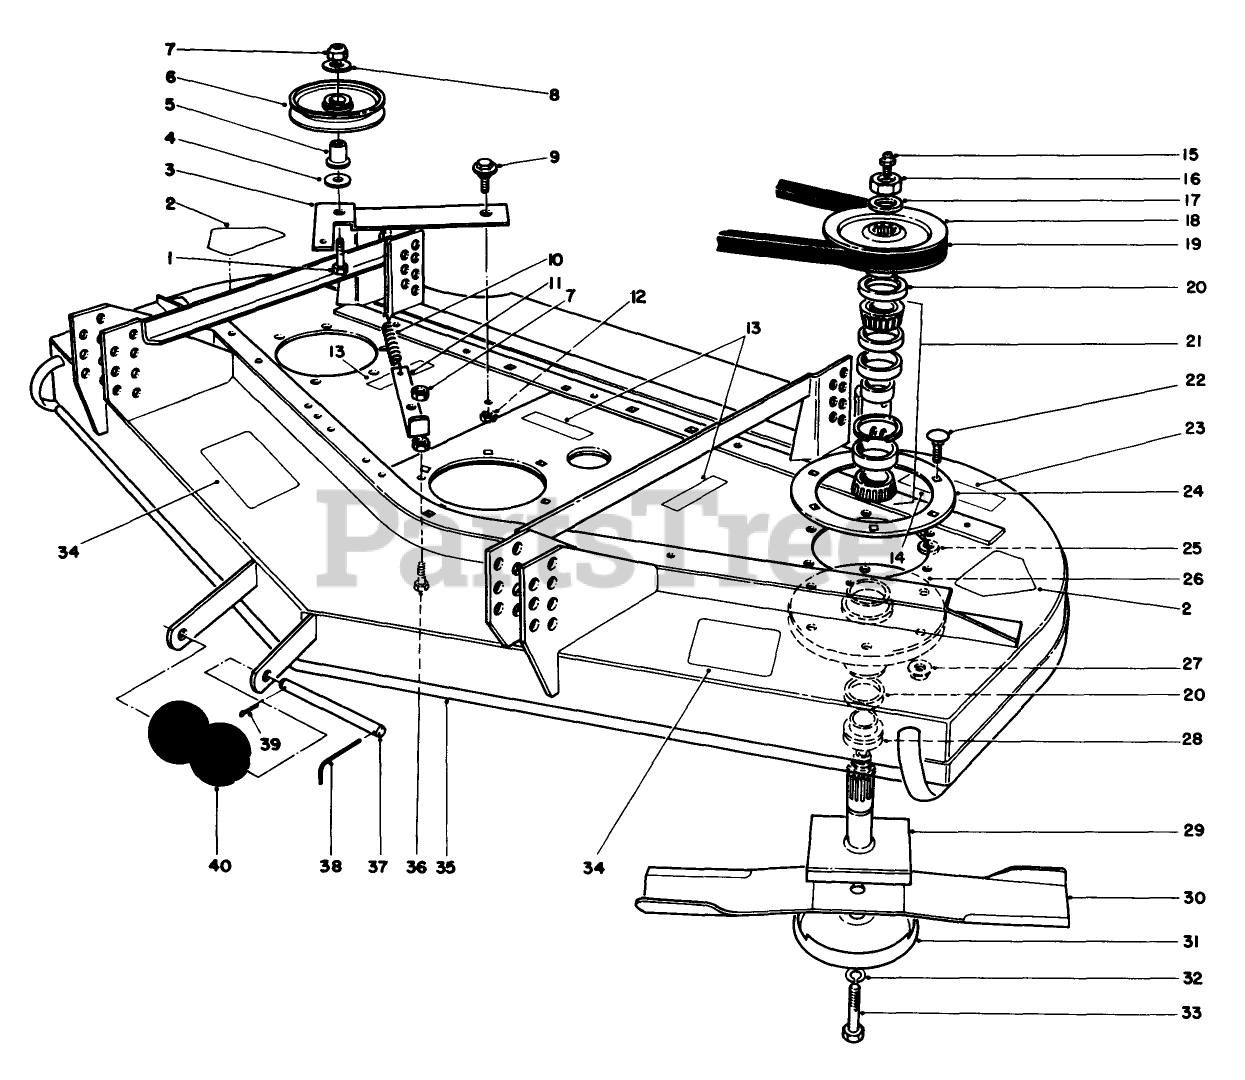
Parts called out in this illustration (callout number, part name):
1	SCREW-HH
1	FITTING-GREASE
2	DECAL-DANGER
2	NUT-HEX
3	Lever-Deck
3	WASHER
4	WASHER
4	PULLEY & HUB WA
5	BUSHING-PULLEY
5	SEAL-OIL
6	Pulley (Incl. Ref. #4 & 5)
6	BEARING ASM
7	NUT-LOCK, SIDE
7	HOUSING-SPINDLE
8	WASHER-FLAT
8	SPACER
9	SCREW-SHOULDER
9	SHAFT
10	SPRING-EXTENSION, DECK
11	Anchor-Spring
12	NUT-LOCK, NI
13	DECAL-DANGER
14	DECAL-TORQUE
15	FITTING-GREASE
16	NUT-HEX
17	WASHER
18	PULLEY & HUB WA
19	V-BELT, DECK
20	SEAL-OIL
21	BEARING ASM
22	SCREW-CARR
23	DECAL-WARNING
24	SUPPORT-DECK, RING
25	WASHER-FLAT
26	HOUSING-SPINDLE
27	NUT-HF
28	SPACER
29	SHAFT
30	Blade
31	Cup-Scalp
32	WASHER-LOCK
33	SCREW-BLADE
34	DECAL-DANGER, THROWN OBJECT
35	RD CUTTING DECK WA R
36	SCREW-HH
37	SHAFT-ROLLER
38	PIN-SPECIAL
39	PIN-COTTER
40	ROLLER
